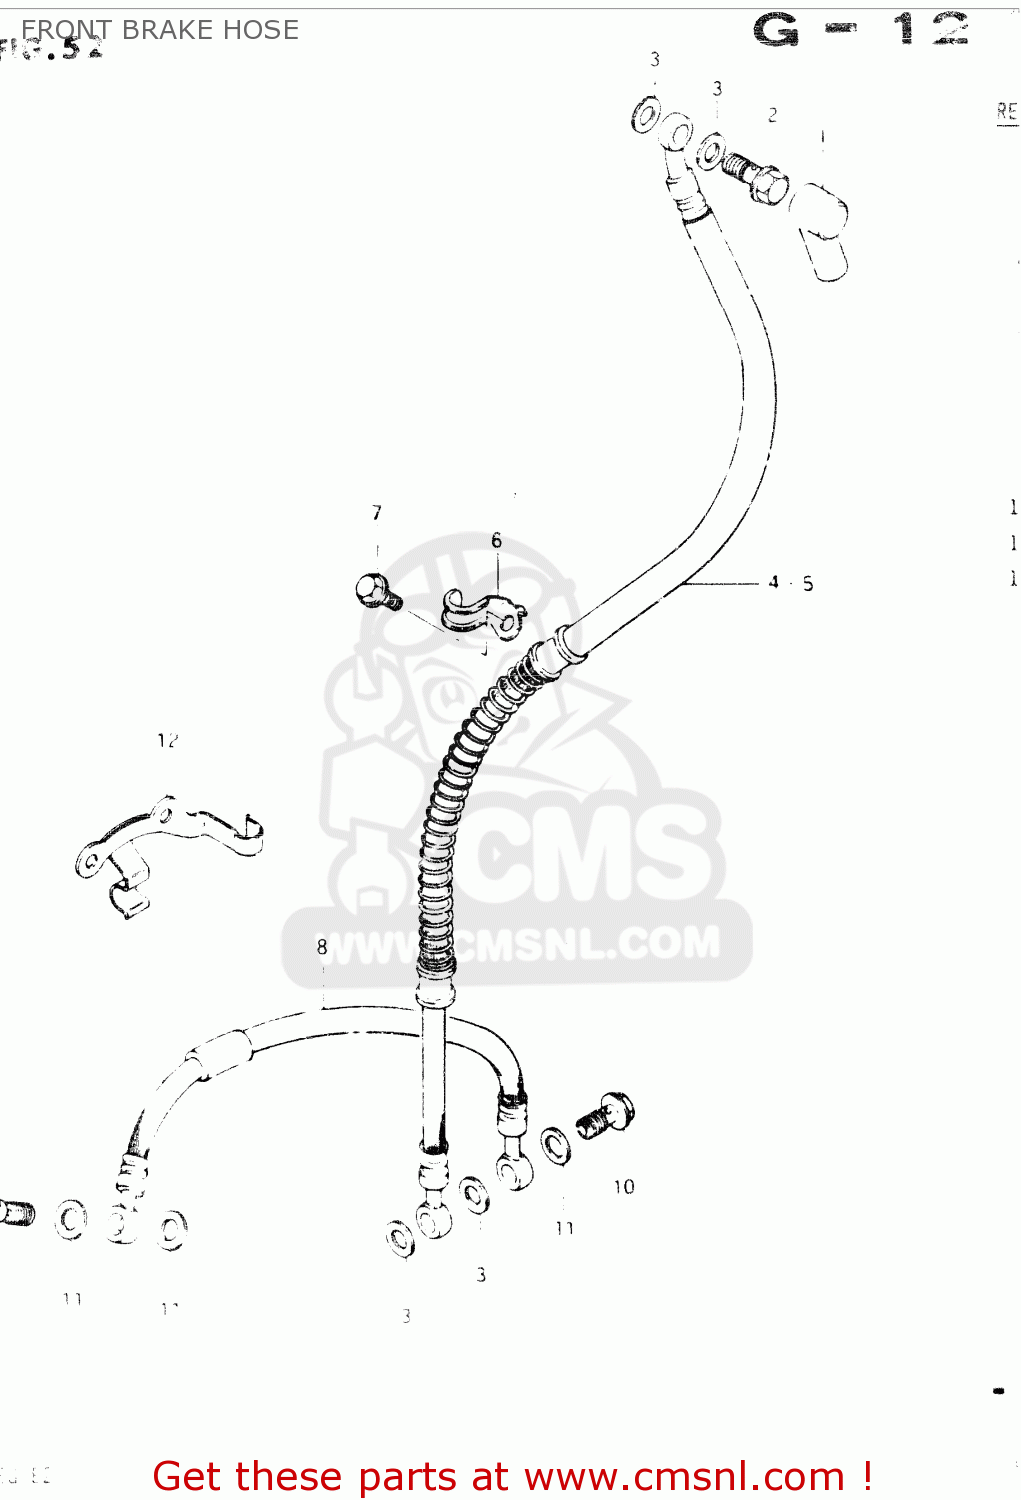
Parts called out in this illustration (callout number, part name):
1	BOOT,MASTER CYLINDER
2	BOLT UNION
3	WASHER(10X15X1.5)
4	HOSE,FR BRAKE
5	HOSE, BRAKE (FLAT HANDLEBAR)
6	GUIDE,BRAKE HOSE NO.3
7	BOLT
8	HOSE,ANTI NOSE
9	BOLT UNION
10	BOLT UNION
11	WASHER(10X15X1.5)
12	CLAMP,BRAKE HOSE,LEFT
